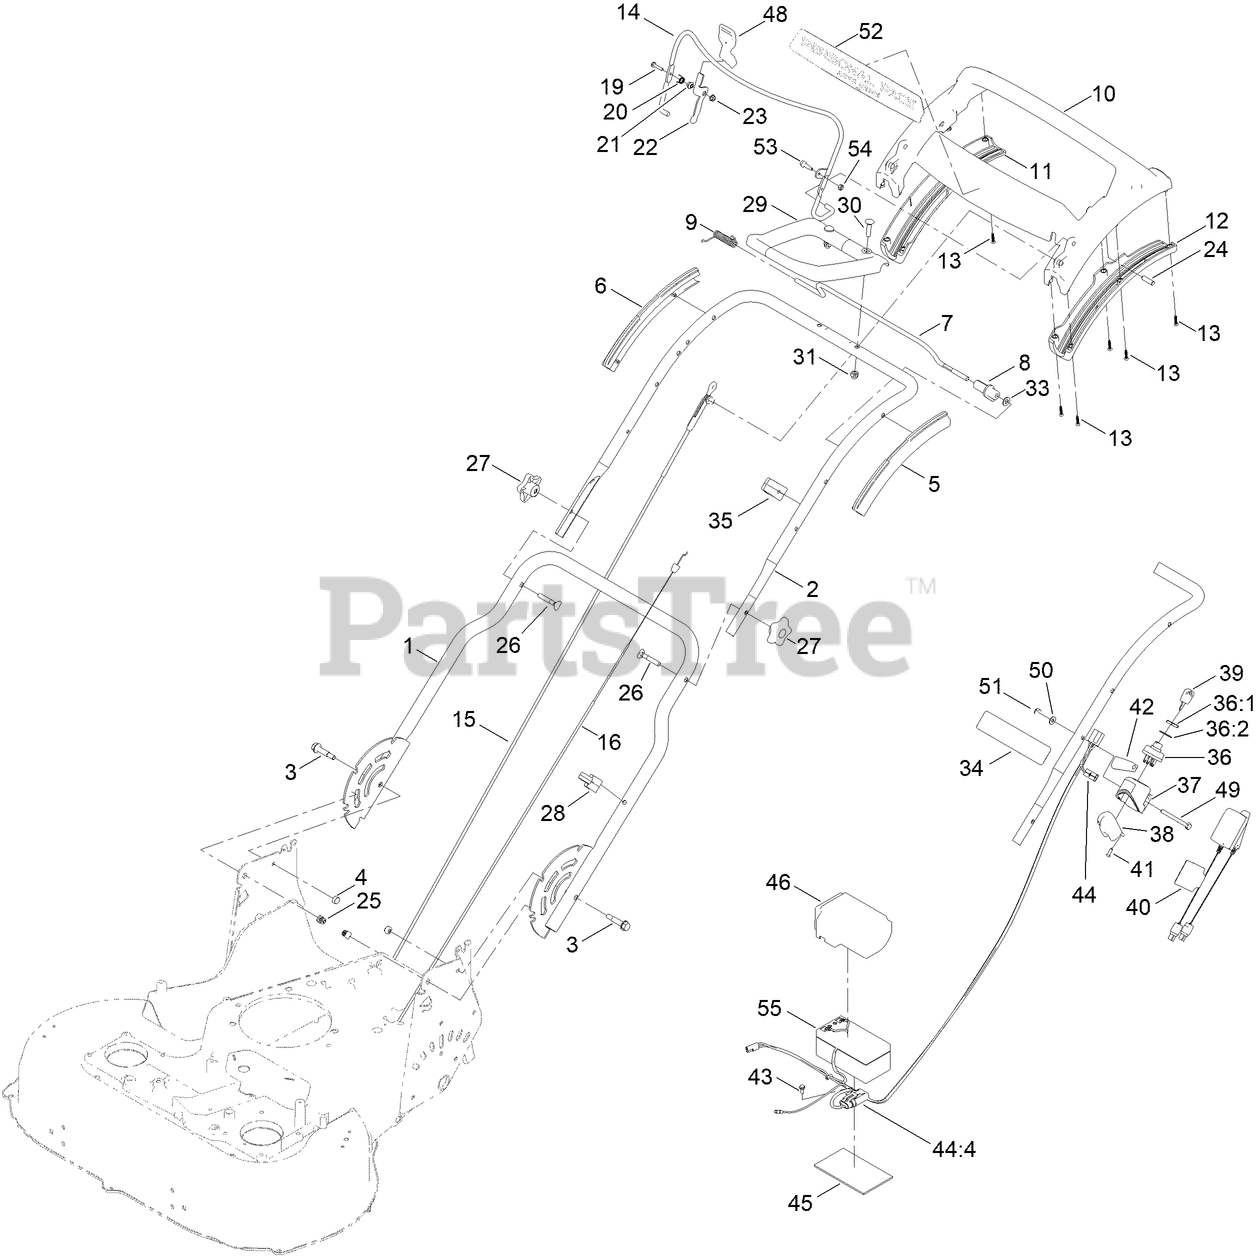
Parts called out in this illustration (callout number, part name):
1	HANDLE-LOWER, ASM
2	HANDLE-UPPER
3	BOLT-SHOULDER, HHF
4	NUT-LOCK, NI
5	GUIDE-CURVED, LH (RWD)
6	GUIDE-CURVED, RH (RWD)
7	ROD-CONTROL, TRACTION
8	LEVER-TRACTION, RWD
9	SPRING-TORSION
10	HANDLE-PERSONAL PACE, CURVED
11	BOTTOM-HANDLE, RH
12	BOTTOM-HANDLE, LH
13	SCREW-PPH
14	BAIL-BRAKE, BBC WELDED
15	CABLE-BRAKE
16	CABLE-TRACTION
19	SCREW-HWH
20	SPRING-TORSION
21	SPACER
23	NUT-LOCK, FLANGE
24	PIN-HANDLE, PP
25	PLUG-SQUARE
26	SCREW-HANDLE
27	KNOB-HANDLE
28	GUIDE-CABLE
29	HANDLE-ASSIST
30	BOLT-CARRIAGE
31	NUT-ACORN
33	WASHER-PLAIN
34	DECAL-BATTERY CHARGING
35	ANCHOR-CABLE
36	SWITCH-STARTER
36:1	NUT-HH
36:2	WASHER-LOCK
37	HOUSING-SWITCH, KEY
38	COVER-SWTCH
40	CHARGER, BATTERY (12V)
41	SCREW-PLASTIC, PPH
42	DECAL-SWITCH, IGNITION
43	SCREW-TAPTITE
44	HARNESS-WIRE
44:4	FUSE-40 AMP
45	FOAM-BATTERY
46	COVER-BATTERY
49	SCREW-HH
50	WASHER-FLAT
51	NUT-LOCK, NI
52	DECAL-HANDLE, PP
53	SCREW-SHOULDER
54	NUT-HEX
55	BATTERY-WET
